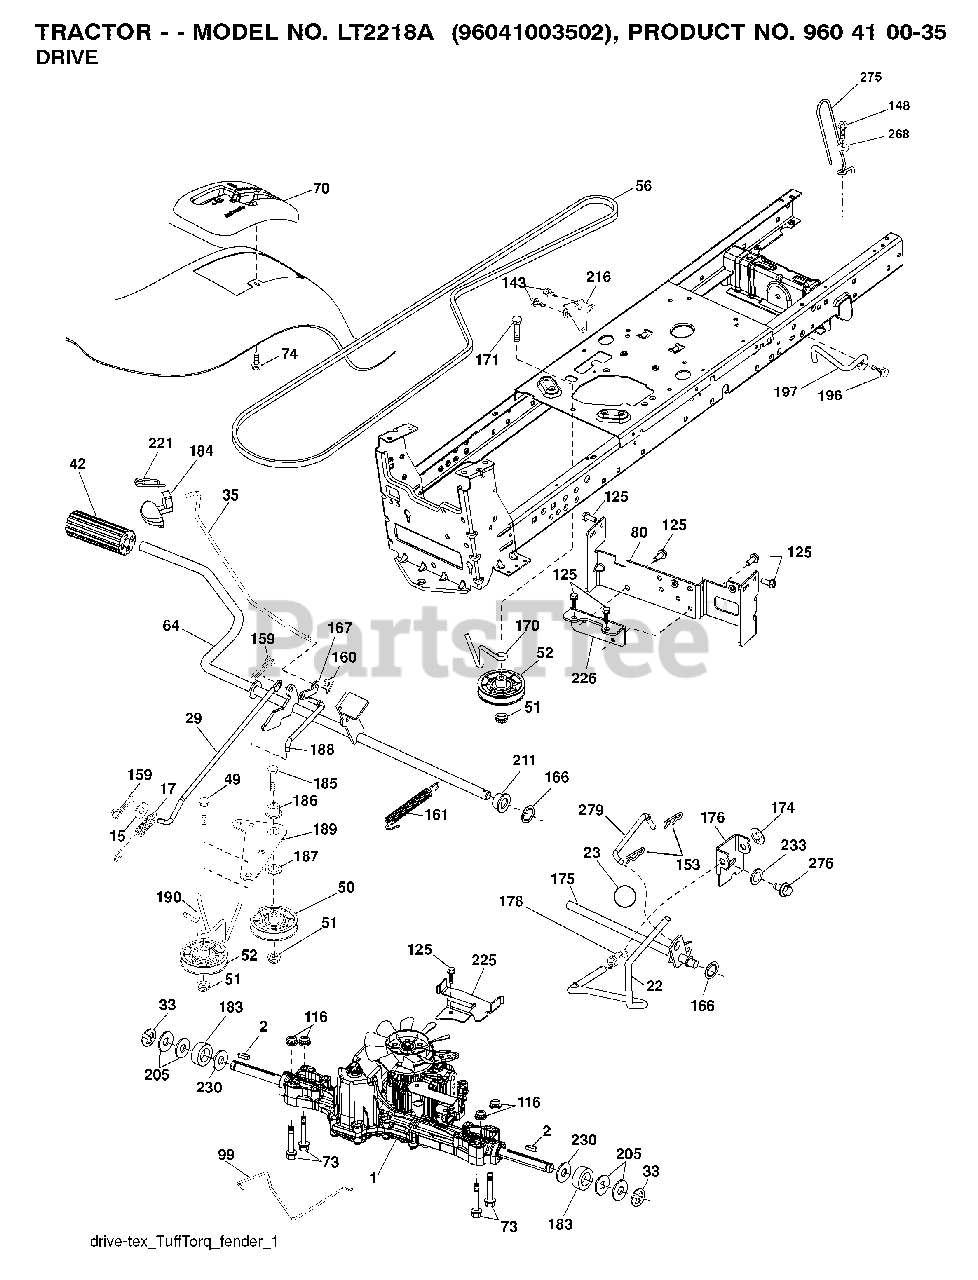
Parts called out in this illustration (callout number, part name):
2	SQUARE KEY
17	SPRING.BRAKE.K46.GREEN
22	ROD.SHIFT.FENDER.TLT.2006
23	PISTOL KNOB
29	ROD.BRAKE.K46
33	E-RING LT
35	ROD.BRKAE.PARKING.STEALTH
42	PEDAL COVER T
49	BOLT
50	IDLER.FLAT.910.OFFSET
51	NUT LOCK FLG 3/8-16 UNC
52	IDLER.V-GROOVE.910.OFFSET
64	SHAFT.ASM.PEDAL.BRAKE.
70	CONSOLE.SHIFT.STL.HYD.BLACK
73	BOLT HEX 5/16-18 GR 5
74	SCREW.HI-LO.CONSOLE
80	STRAP TORQUE
99	ROD ASM BYPASS
116	NUT LOCK HEX FLANGE 5/16-18
125	SCREW
148	SCREW, 3/8-16X3/4
153	RETAINER M
159	COTTER PIN
160	RETAINER CLIP
161	SPRING.RETURN.CLUTCH.2006
166	NUT.PUSH.625.2006
167	LATCH.BRAKE.SPRING
170	KEEPER.V-IDLER.CENTER.
171	BOLT
174	NUT.PUSH.500.2006
175	SHAFT ASM SHIFT
176	ARM.CLEVIS.ROD.SHIFT
178	SPRING.SHIFT.GT2006
183	SPACER AXLE
184	HANDLE.PRKG.BRAKE.STLTH.TX.RED
186	SPACER.RETAINER
187	WASHER 12/32X2X10GA
188	LINK.CLUTCH.GROUND.DRIVE
189	BELLCRANK.GROUND.DRIVE.TEX.
190	KEEPER.BELLCRANK.DRIVE
197	LINK.CLUTCH.ANIT-ROTAT
211	BUSHING.SHAFT.BRAKE.HAND
216	BRACKET.PULLEY.IDLER.W/TEX
221	RETAINER.SPRING.CLIP.H
225	KEEPER.BELT.TRANSAXLE.K46
226	BRACKET.MOUNT.TORQUE.K46.TLT
230	WASHER.HARDENED
233	WASHER SERRATED
268	WASHER
276	BOLT FIN HEX 7/16-14 X 1
279	LINK SHIFT
